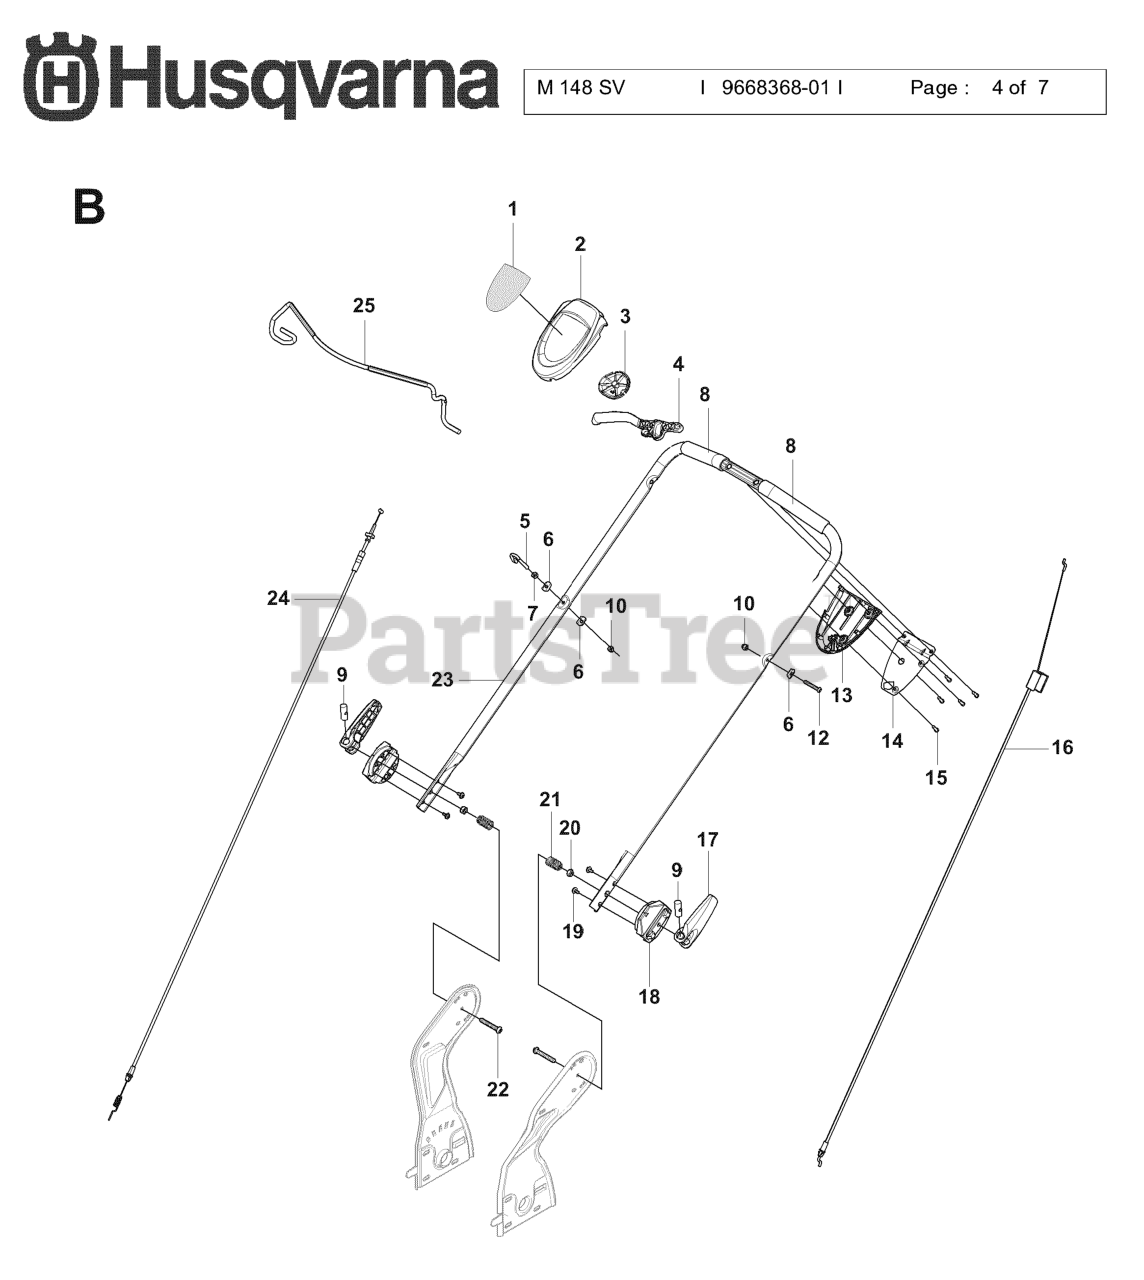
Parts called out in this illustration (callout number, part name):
2	COVER, DRIVE CONTROL BOTTOM
3	PULLEY.CAM.DRIVE.CONTROL.EZ
4	LEVER, DRIVE CONTROL
13	COVER, DRIVE CONTROL, TOP
14	BRACKET, DRIVE CONTROL
15	SCREW ITXPANT T50X16 ZN/FE (A
16	BRAKE WIRE
19	SCREW ITXPANTT M5X10 ZPB (A00
